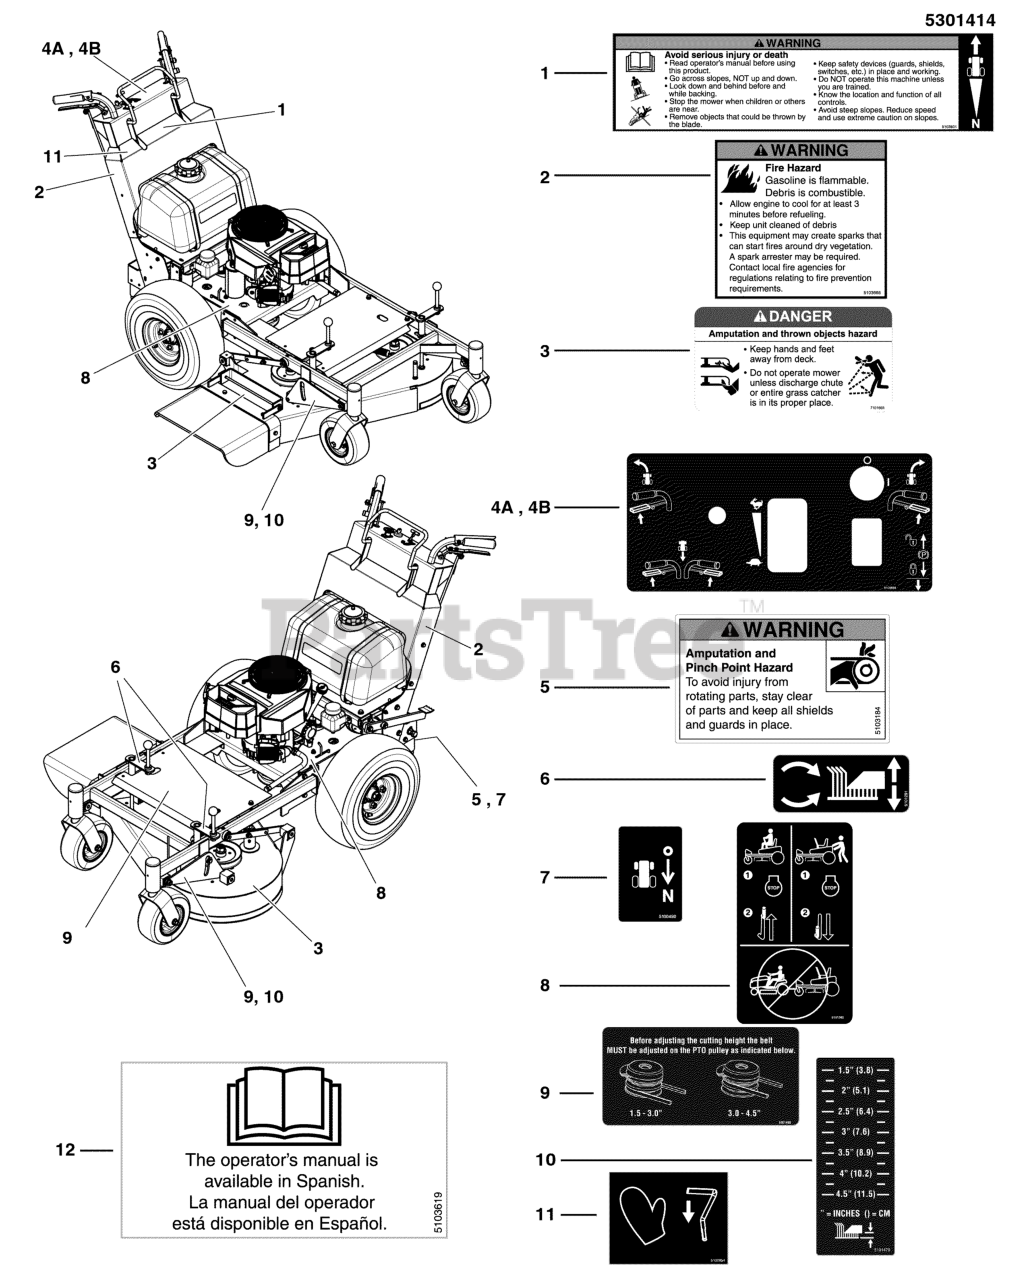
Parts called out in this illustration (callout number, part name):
1	DECAL, WARNING, WALKS
2	DECAL, FIRE HAZARD, 3.25W X 3.0H
3	DECAL, DANGER DO NOT OPERATE W/O DEFLECT
4A	DECAL, CONTROL PANEL, SPDD
4B	DECAL, CONROL PANEL, WB
5	DECAL, WARNING, HAND IN BELT, ENG ONLY
6	DECAL, CUT HEIGHT, SPDD
7	DECAL, PEDAL
8	DECAL, TRANSAXLE RELEASE
9	* DECAL, BELT LOCATION, PTO, SW20
10	DECAL, CUT HEIGHT, SW-20
11	DECAL, OPC, CCW
12	DECAL, MANUAL AVAIL IN SPANISH
